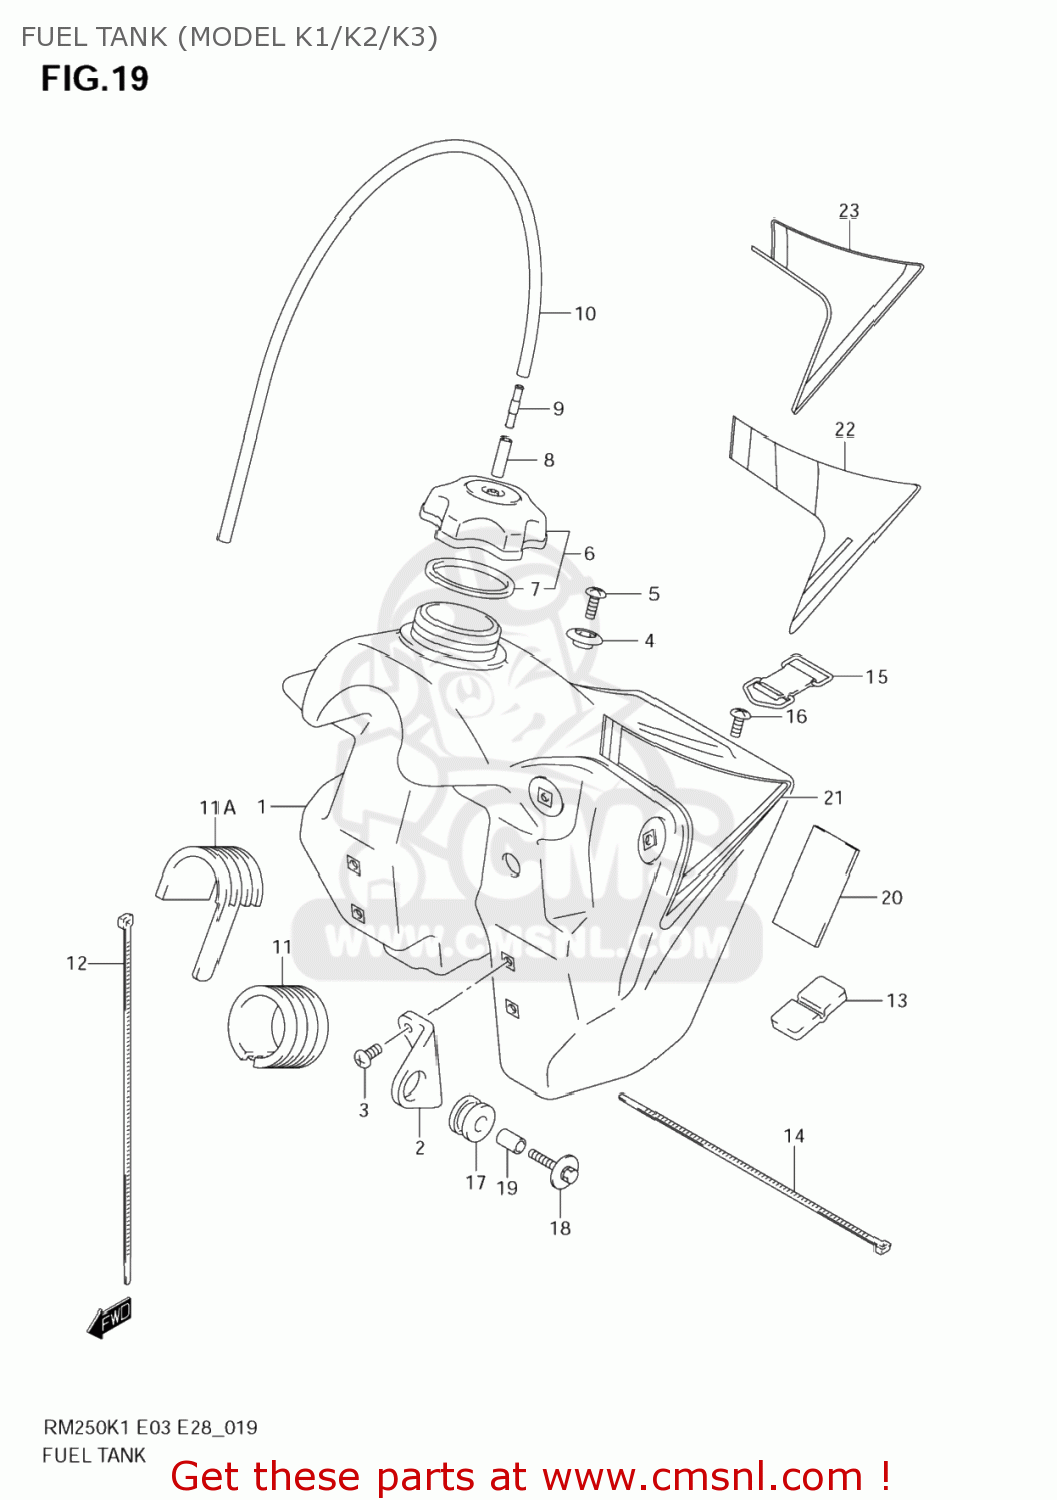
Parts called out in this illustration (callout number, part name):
1	TANK COMP,FUEL
2	BRACKET,FUEL TANK FR
3	SCREW 6X12
4	HOOK,SEAT FR
5	SCREW
6	CAP SET,FUEL TANK
7	GASKET,CAP (NAS)
8	HOSE(5X8.2X600)
9	PLUG,FUEL TANK BREATHER
10	HOSE(5X8.2X600)
11	CUSHION,FUEL TANK NO.1
11A	CUSHION,FUEL TANK
12	CLAMP(L:300)
13	CUSHION
14	CLAMP(L:250)
15	BAND,FUEL TANK RR
16	SCREW
17	CUSHION,MUFFLER
18	BOLT(6X30)
19	SPACER(6.5X9X13.5)
20	PROTECTOR(40X85X5)
21	TAPE SET,FUEL
22	TAPE SET,FUEL TANK
23	TAPE SET,FUEL TANK
